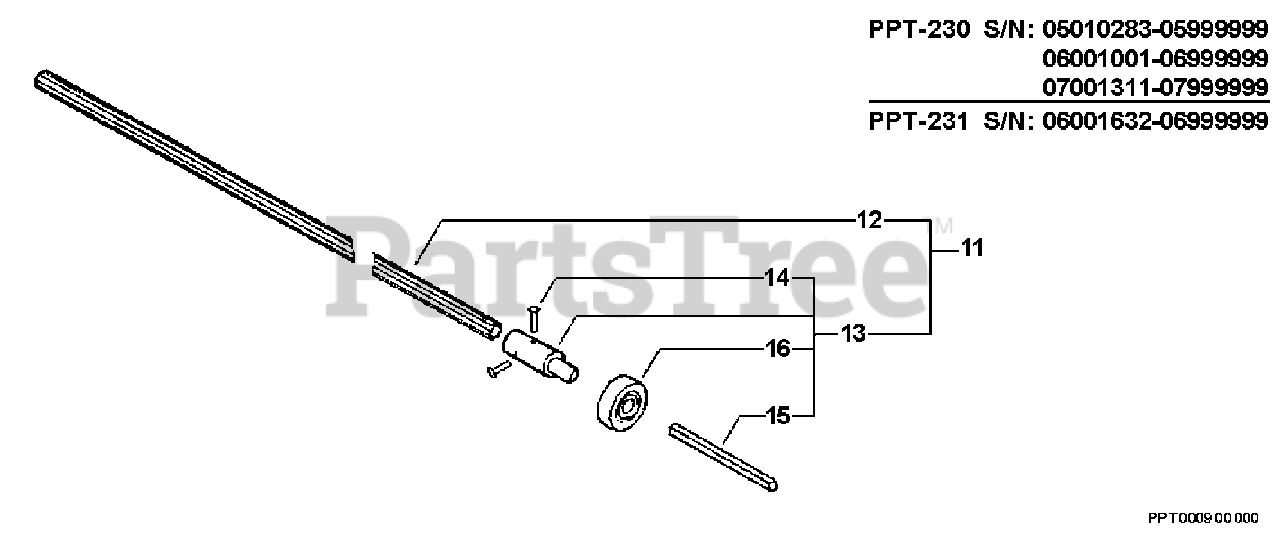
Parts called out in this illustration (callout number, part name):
11	DRIVESHAFT ASSY
12	DRIVESHAFT
13	SHAFT CONNECTOR KIT
16	BEARING, BALL - 6002
